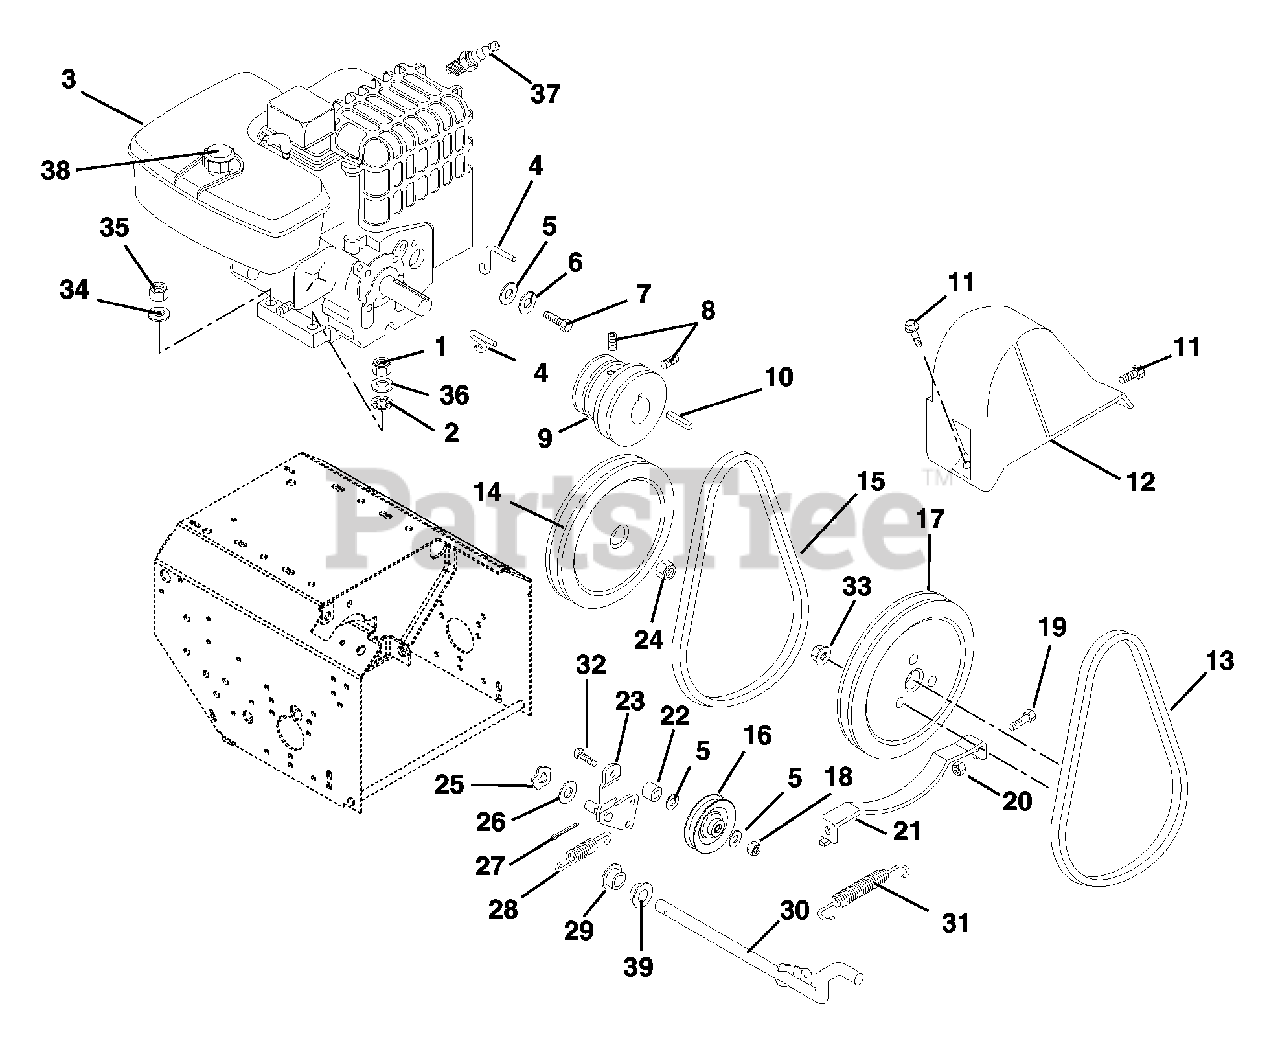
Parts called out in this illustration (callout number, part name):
1	Nut, Locking Center .31-18
2	Washer, Lock Internal .31
3	Engine, 9HP Tecumseh OHV
4	Belt Finger
5	Washer, Flat Steel .38 x .88 x .083
6	Washer, Locking .31 x .078
7	Bolt, Hex .31-24 x .75 Grade 5
8	Screw, Set .31-18 x .38
9	Engine Sheave
10	Key, Straight .25 x 1.75 x .25
11	Screw, Tap .25-20 x .50
12	Belt Cover
14	Pulley-V 8.40 x 1.00 with Key
15	V-Belt,Traction Drive
16	Idler
17	Pulley-V 9.0 x 1.25
18	Nut, Locking Center .31-18
19	Bolt, Hex .25-20 x .50 Grade 5
20	Nut, Locking Center .25-20
21	Belt Retainer
23	Idler Arm
24	Nut, Locking Nylon .63-18
25	Wave Washer
26	Washer, Flat Steel .38 x .81 x .023
27	Pin, Cotter .09 x 1.00
28	Spring, Tension .80 x .73 x 3.06
29	Bushing, Flange Nylon .50 x .63 x .31 x .75
30	Shaft, Activating
31	Spring, Tension .05 x .44 x 3.37
32	Bolt, Hex .31-18 x 1.25 Grade 5
33	Nut, Locking Flange .31-18
34	Washer, Locking .31 x .097 Heavy
35	Nut, Hex .31-18
36	Washer, Flat Steel .344 x .688 x .065
37	Plug, Spark
38	Fuel Cap
39	Bushing, Flange .50 x.63 x.50 x.75
